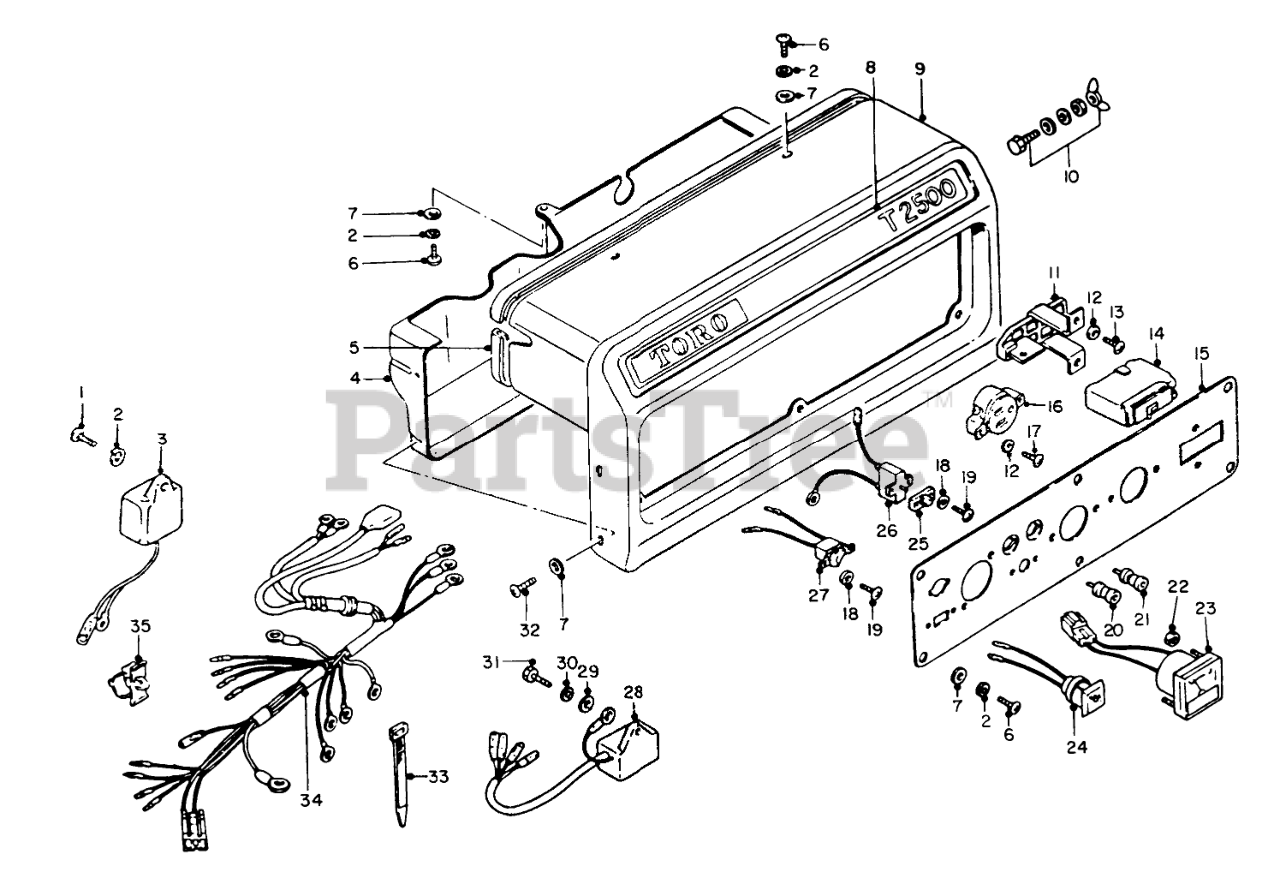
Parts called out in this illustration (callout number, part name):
1	Screw
2	Washer
3	X-STR MAG UNIT
4	Panel-Rear
6	SCREW
7	WASHER
8	Emblem-Toro T2500
9	Panel-Control
10	GROUND TERMINAL
11	BREAKER HOLDER
12	Washer
13	Screw
14	Circuit Breaker (21 A)
15	Plate-Panel
16	Receptacle
17	Screw
18	Washer
19	Screw
20	TERMINAL-
23	Meter-Voltage
26	Protector-Circuit
27	Switch
28	OIL LEVEL UNIT
29	Washer
30	LOCKWASHER
32	Screw
33	Clamp
34	Harness-Control
35	Clamp
